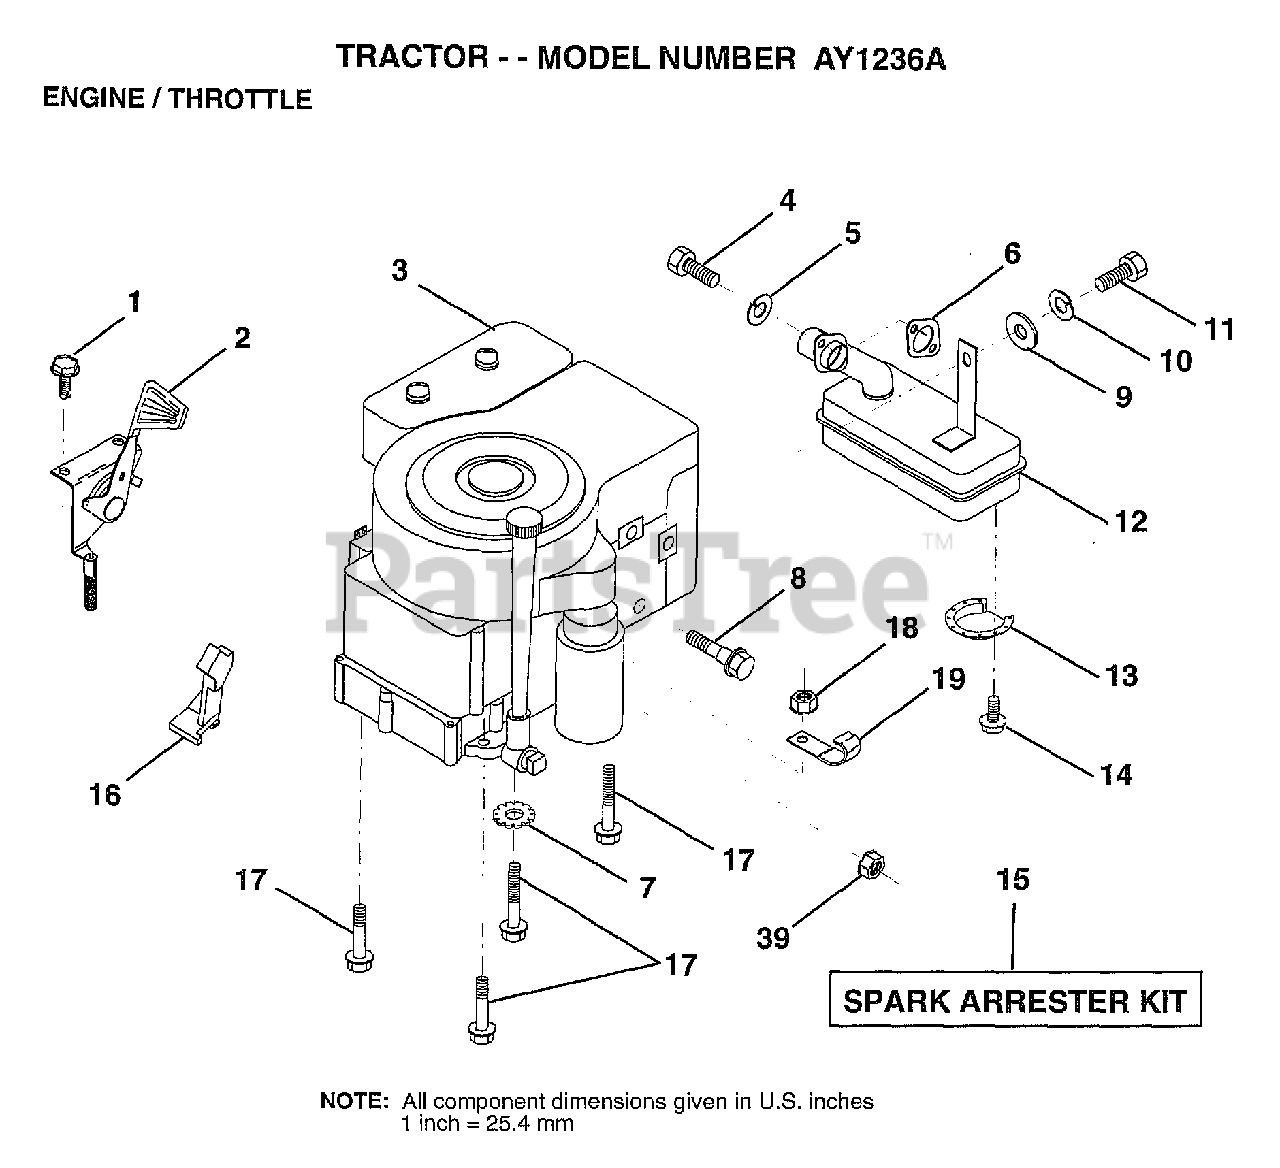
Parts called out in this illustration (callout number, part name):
1	SCREW.1/4-20X1/2
4	SCREW
5	LOCKWASHER
6	GASKET ENG 1 313 LD TIN PLATED
7	LOCKWASHER
8	BOLT T
10	LOCKWASHER
12	MUFFLER
13	DEFLECTOR.222573
16	"STOP,DASH THROTT"
17	SCREW LT
18	NUT
19	CLIP T
39	NUT
